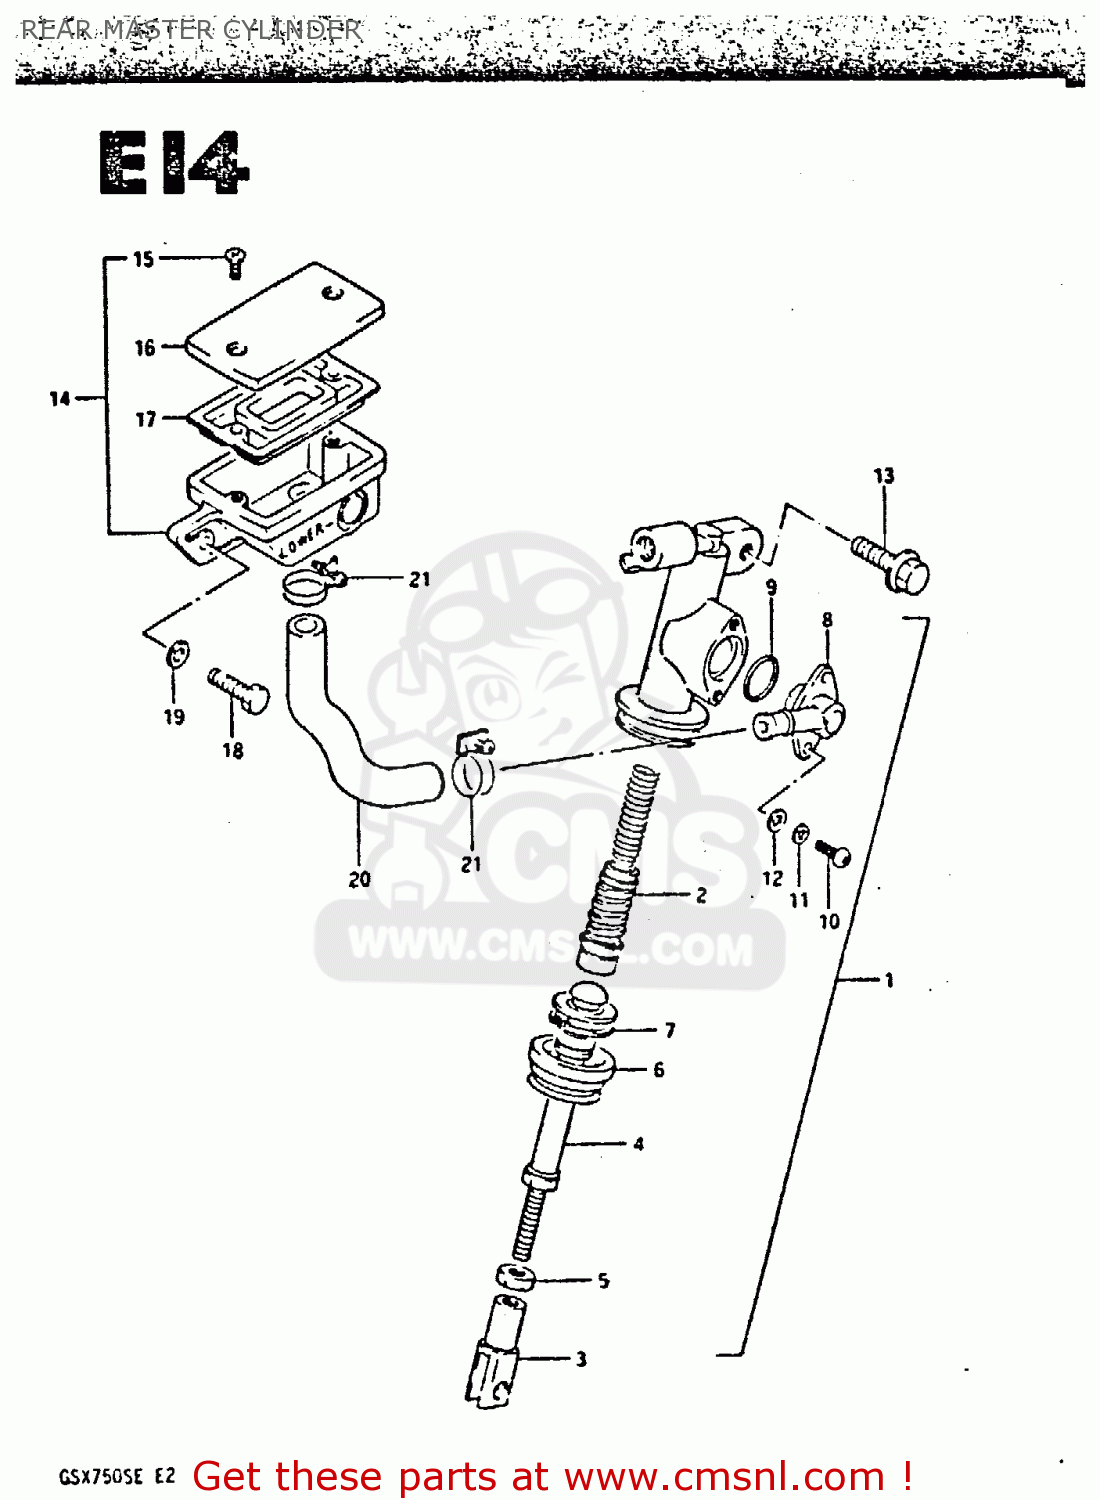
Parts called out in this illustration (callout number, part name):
1	CYLINDER ASSY,RR MASTER
2	PISTON/CUP SET
3	YOKE
4	ROD,PUSH
5	NUT,MASTER CYLINDER
6	BOOT
7	CIRCLIP
8	CONNECTOR,HOSE
9	O RING
10	SCREW
11	LOCK WASHER
12	WASHER
13	BOLT
14	RESERVOIR TANK ASSY
15	SCREW
16	CAP
17	18
18	BOLT 6X16
19	WASHER,LOCK
20	HOSE
21	CLAMP
